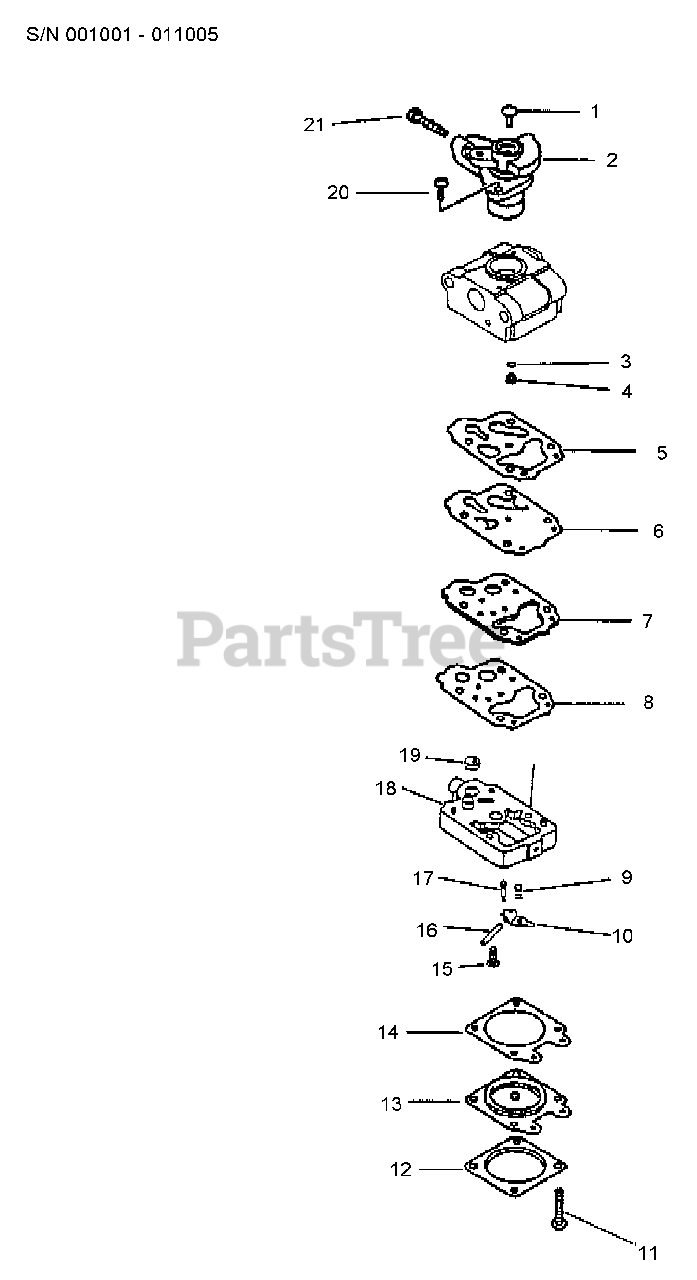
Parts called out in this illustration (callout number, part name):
1	PLUG, WELCH
2	VALVE, THROTTLE
4	JET, MAIN
5	GASKET, PUMP
6	DIAPHRAGM, PUMP
7	PLATE, PUMP
8	GASKET, PLATE
9	SPRING, METERING LEVER
10	LEVER, METERING
12	COVER, METERING
13	DIAPHRAGM, METERING
14	GASKET, METERING
15	SCREW, METERING LEVER PIN
16	PIN, METERING LEVER
17	VALVE, INLET NEEDLE
18	BASE, PURGE
19	STRAINER
21	SCREW, IDLE ADJUST
